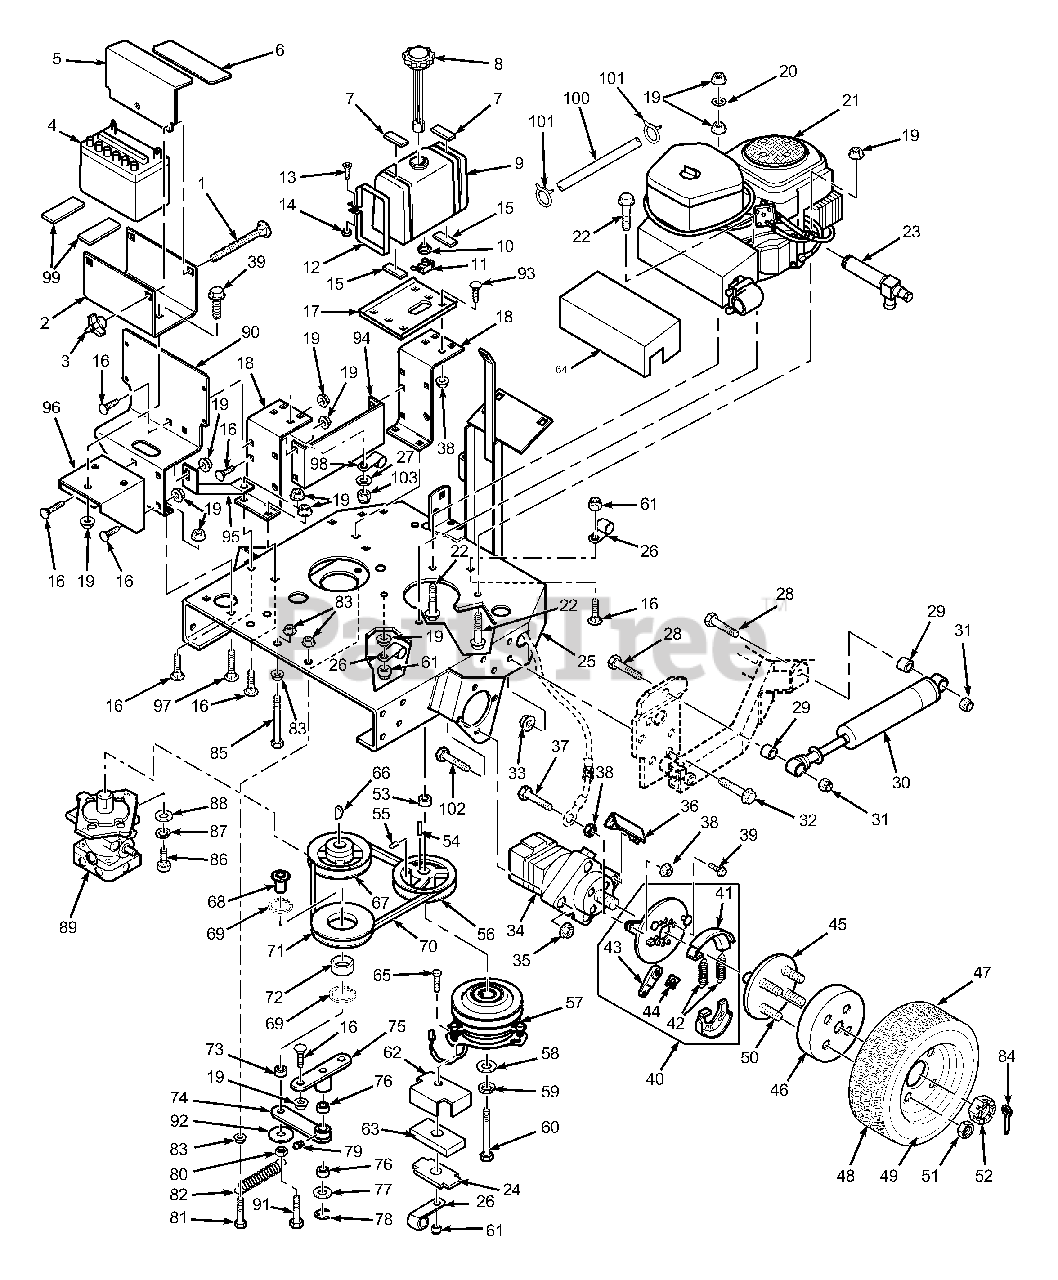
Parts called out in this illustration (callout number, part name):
1	Carriage Bolt, 1/4-20 x 6"
2	Battery Box
3	Nut, Wing 1/4-20
4	Battery
5	Battery Cover
6	Insulation, Battery Cover
7	Pad, Fuel Tank Strap
8	Cap, Fuel Tank
9	Fuel Tank Assy.
10	Bushing, Fuel Tank Valve
11	Fuel Shut Off Valve
12	Strap, Fuel Tank
13	Phil RDHD Machine Screw 1/4-20 x 2"
14	Hex Nut, 1/4-20
15	Pad, Fuel Tank Support
16	Carriage Bolt, 5/16-18 x 3/4"
17	Support, Fuel Tank
18	Bracket, Fuel Tank Support
19	Serr. Fl. Hex Nut 5/16-18
20	Lockwasher, 5/16 Int. Tooth
21	Engine, 23 HP Kohler CV, (Spec PS-75523)
22	Hex Head CPSCR, 5/16-18 x 1-3/4"
23	Oil Drain Extension
24	Plate, Backing
25	Engine Deck
26	Wire Loom, .50 I.D.
27	Washer, 1/4 (.312 x .750 x .065)
28	Bolt, Hex Head 1/2-13 x 2"
29	Sleeve, Shock Absorber Mount
30	Shock Absorber
31	Hex Locknut, Elastic Stop 1/2-13
32	Serr. Fl. Hex Head CPSCR, 7/16-14 x 1"
33	Serr. Fl. Hex Nut, 7/16-14
34	Motor - White
35	Lockwasher, 1/2"
36	Anchor, Brake
37	Bolt, Hex Head 1/4-20 x 1-1/4"
38	Serr. Fl. Hex Nut, 1/4-20
39	Serr. Fl. Hex Head CPSCR, 5/16-18 x .75"
40	Parking Brake Assembly
41	Brake Pads- Pair
42	Springs - Pair
43	Actuating Arm,
45	Hub Assembly
46	Brake Drum
47	Rim and Tire Assembly
48	Tire 20 x 10 x 10, 4 Ply
49	Rim Only
50	Bolt, Hub
51	Wheel Nut
52	Castle Nut, 1.0-20 UNEF
53	Spacer, Clutch
54	Key, 1/4 x 1/4 x 1-1/2"
55	Hex Socket Set Screw,
56	Pulley, Engine Pump Drive
57	Clutch, Electric (Ogura)
58	Flatwasher, 7/16 (.469 x
59	Lockwasher, 7/16"
60	Bolt, Hex Head 7/16-20
61	Hex Locknut, Elastic
62	Backing Plate, Clutch Stop
63	Rubber Pad, Clutch Stop
64	Heatshield, Muffler
65	Bolt, Hex Head 5/16-18
66	Key, Woodruff 3/16 x 5/8"
67	Pulley, Pump Input
68	Sleeve, Idler
69	Ring, Retaining, 1-9/16
70	Belt, Pump Drive
71	Pulley, Idler-Traction Drive
72	Bearing, Idler Pulley
73	Spacer, Idler
74	Pump Idler Arm
75	Idler Pivot Base
76	Bushing, Oillube
77	Flatwasher, 3/4"
78	Ring, Retaining, 3/4"
79	Grease Fitting
80	Hex Nut, Jam 3/8-16
81	Bolt, Hex Head 3/8-16
82	Spring, Pump Drive Idler
83	Serr. Fl. Hex Nut, 3/8-16
84	Cotter Pin, 5/32 x 1.50"
85	Bolt, Hex Head 3/8-16 x 5"
86	Socket Head CPSCR, 1/2-13
87	Lockwasher, 1/2"
88	Flatwasher, 1/2 (.516 x. 938 x .105)
89	Pump, Sundstrand
90	Bracket, Oil Tank Support
91	Bolt, Hex Head 3/8-16
92	Washer 2" OD, 3/8 ID,
93	Carriage Bolt, 1/4-20 x 3/4"
94	Guard, Pulley
95	Gusset, Battery Box
96	Support, Battery Box
97	Carriage Bolt, 5/16-18 x 1"
98	Wire Loom, .75" I.D.
99	Rubber Pad
100	Fuel Hose, Order by
101	Clamp, Fuel Hose
102	Bolt, 1/2-13 x 2.50"
103	Nut, 1/4-20 Elastic Stop
